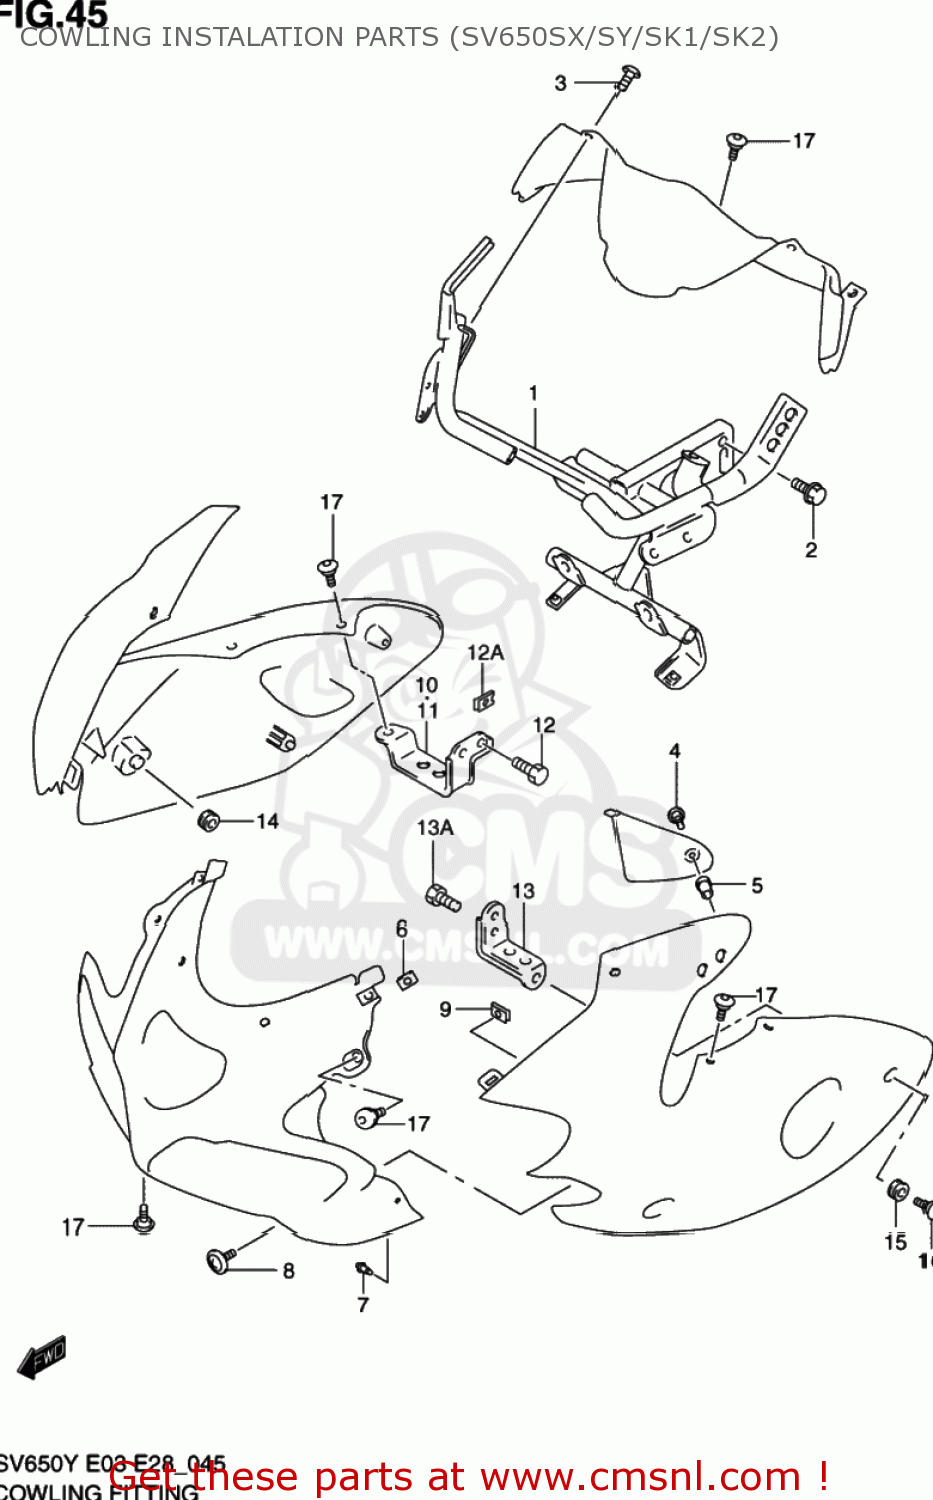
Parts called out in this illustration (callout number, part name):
1	BRACE,COWLING
2	BOLT
3	SCREW 5X12
4	SCREW 5X20
5	NUT
6	NUT,COWL
7	CLIP(BLACK)
8	SCREW
9	NUT
10	BRACKET,SIDE COWLING UP,R
11	BRACKET,SIDE COWLING UP,L
12	BOLT
12A	NUT,FR FENDER
13	BRACKET,SIDE C
13A	BOLT
14	CUSHION
15	CUSHION
16	SCREW(6X20)
17	SCREW(5X16)
